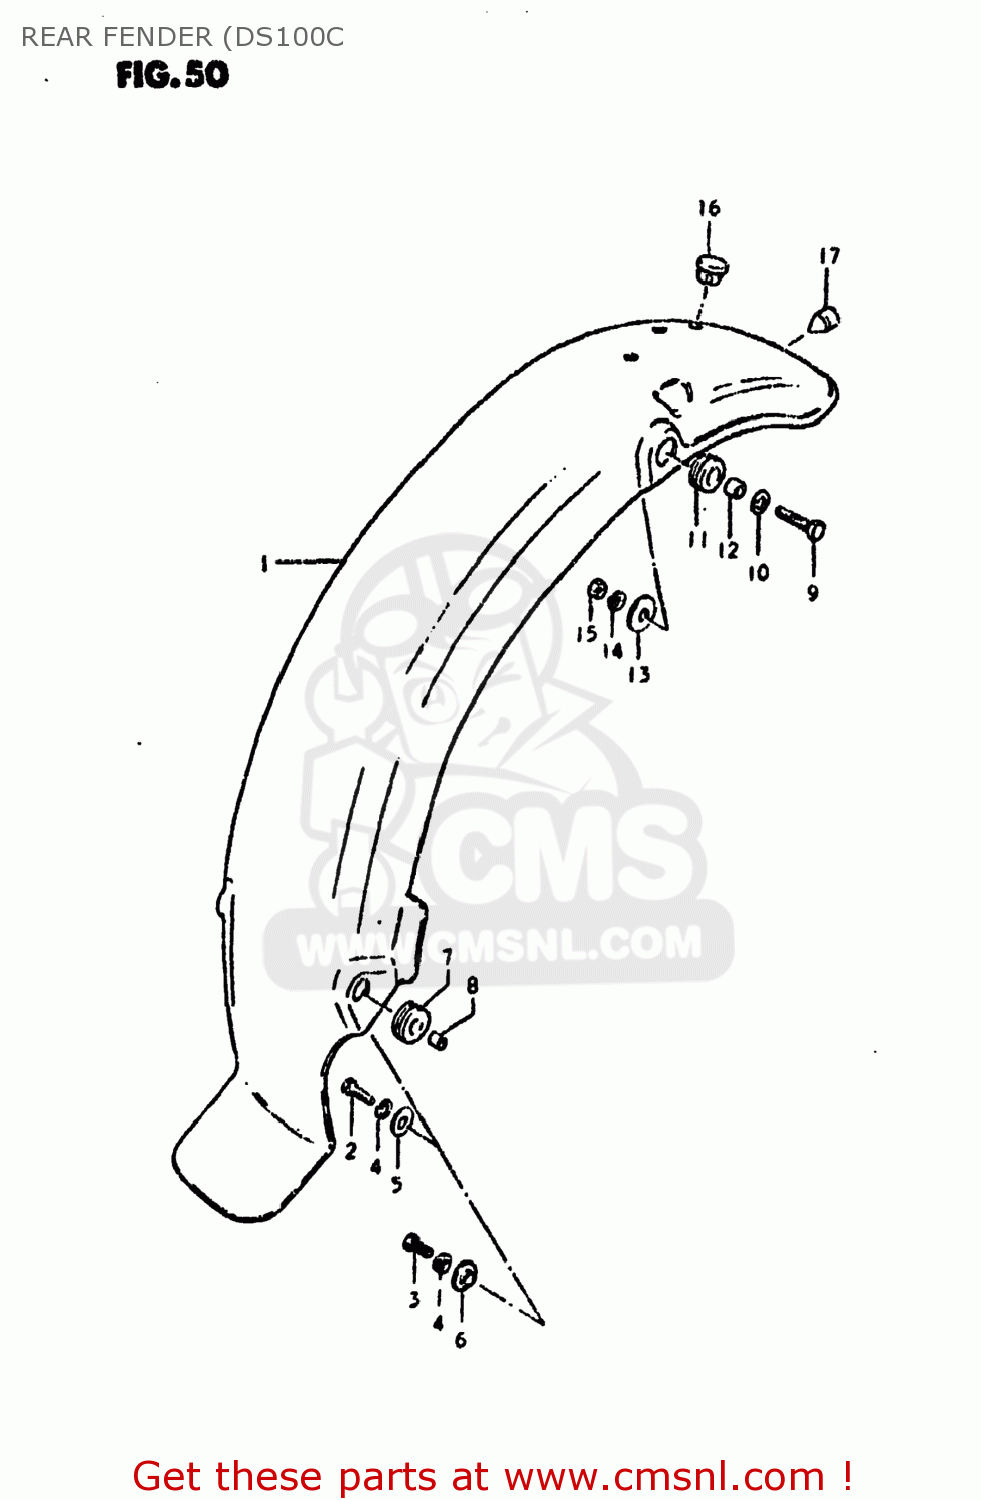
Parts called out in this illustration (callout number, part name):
1	FENDER,REAR
2	BOLT
3	BOLT, UPPER
4	LOCK WASHER
5	WASHER (6.5X20X1.2)
6	WASHER
7	CUSHION
8	SPACER (6.3X9.1X6.7)
9	BOLT (8X30)
10	WASHER
11	CUSHION
12	SPACER (8.2X12X7.5)
13	WASHER(8.5X26X1.2)
14	LOCK WASHER
15	NUT
16	CUSHION
17	CUSHION
